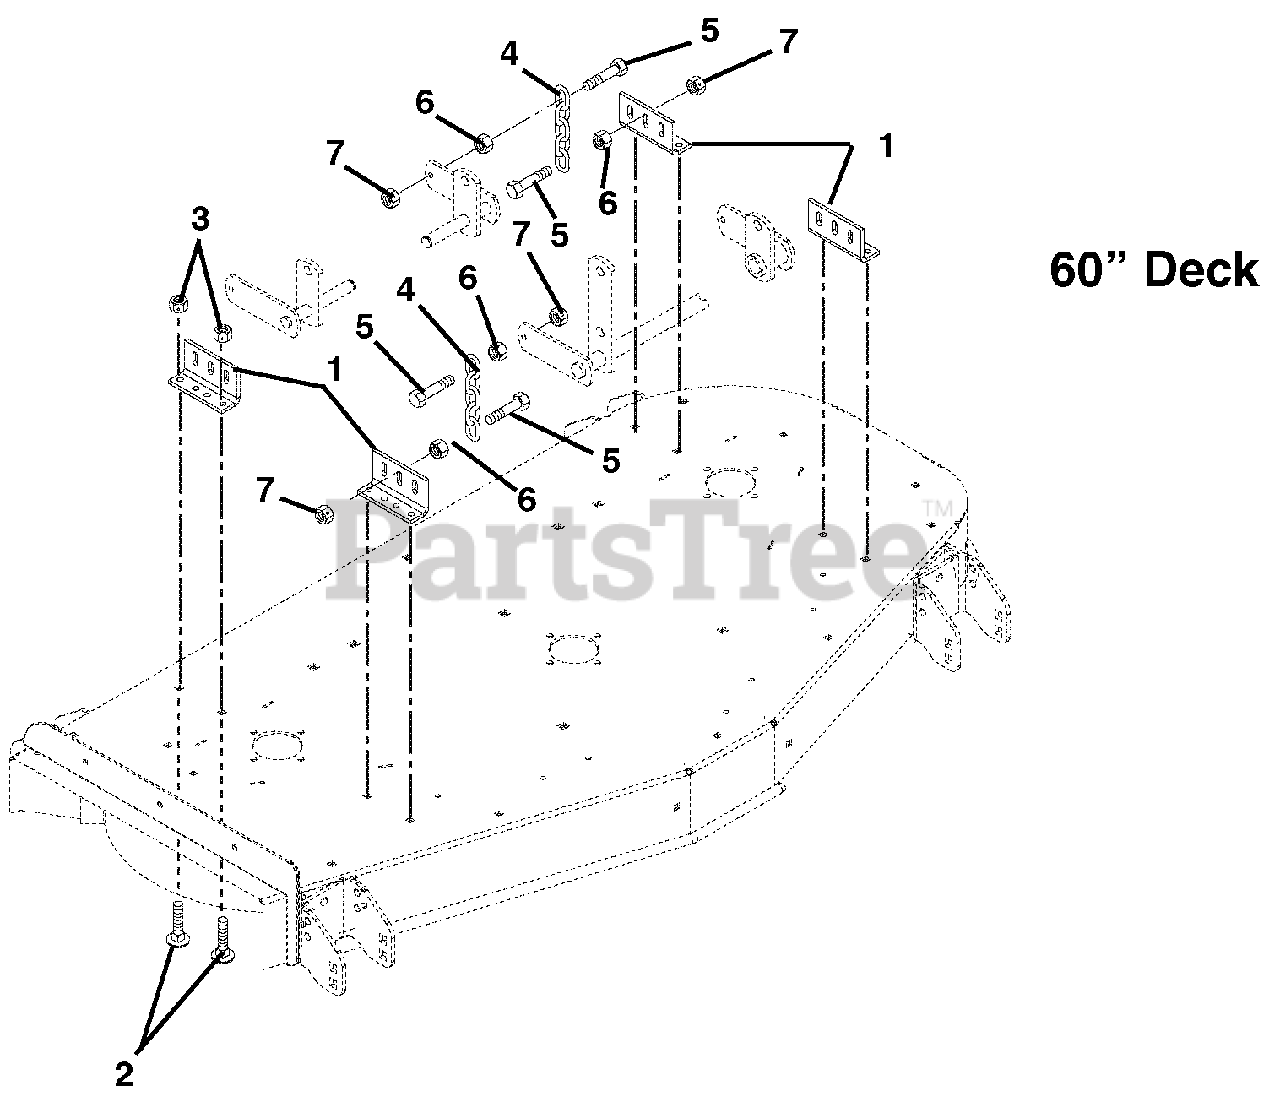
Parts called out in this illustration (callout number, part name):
1	Bracket, Mower Mounting
2	Bolt-Round Head Square Neck .38-16 x 1.00 Grade 2
3	Nut-Locking-Top-Flange .38-16
4	Chain, Link
5	Bolt-Hex .50-13 x 2.00 Grade 5
6	Nut, Spin Lock Flange .5-13
7	Nut-Locking-Top-Flange .50-13
